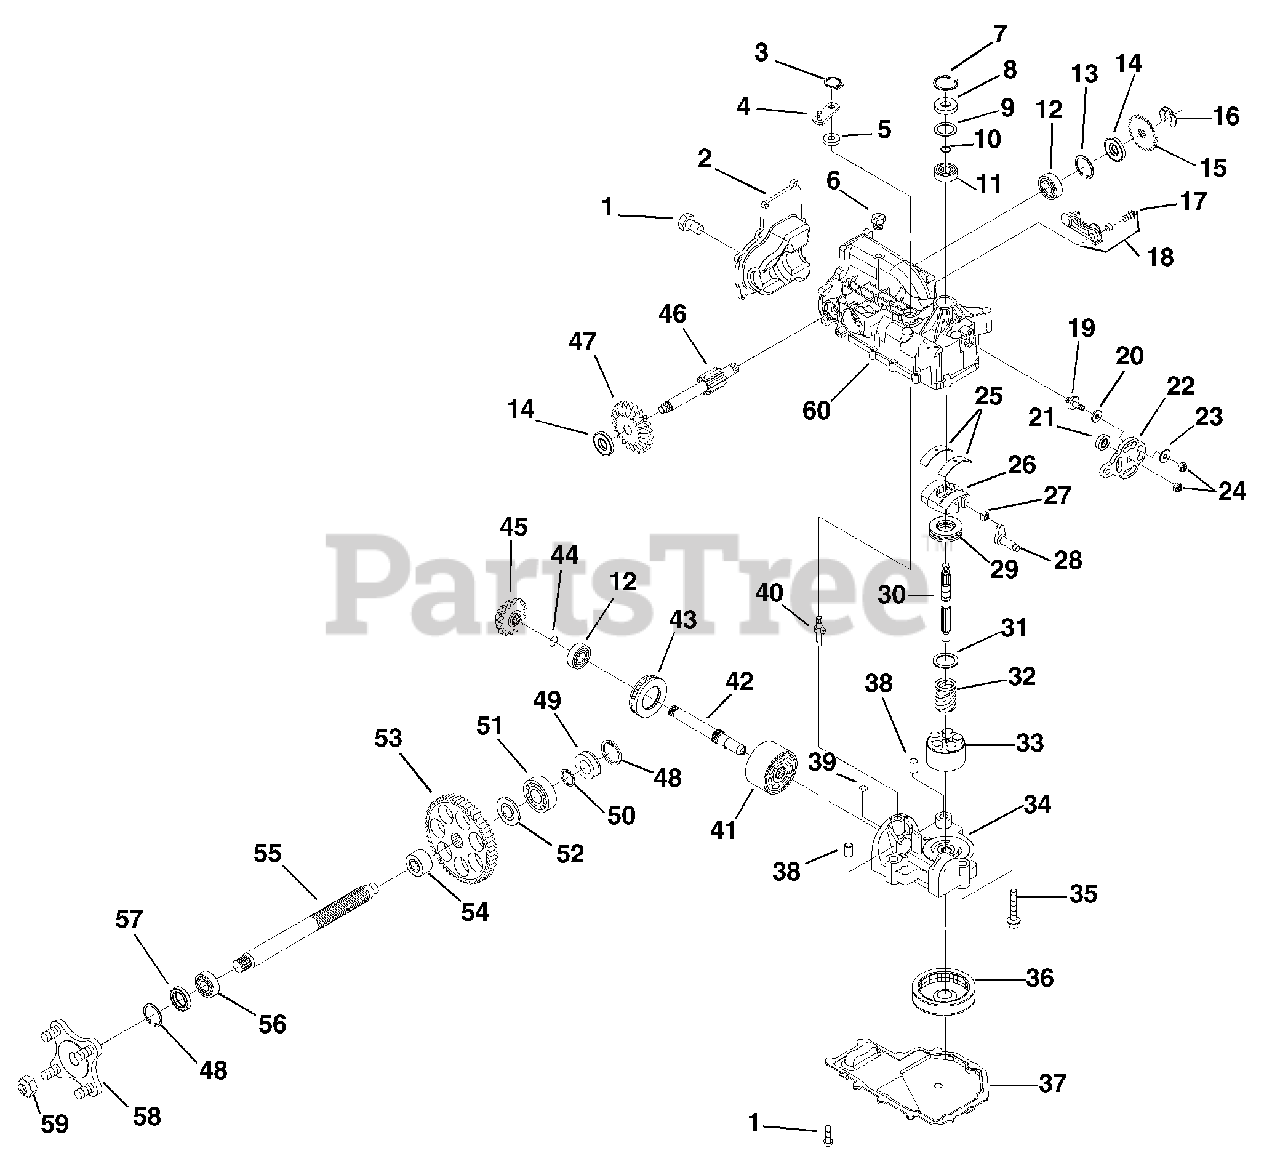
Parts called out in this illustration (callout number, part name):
2	COVER, END IZT
3	RING. RETAINING1
4	ARM. BYPASS
5	SEAL, LIP
6	Plug-Plastic
7	RING. RETAINING
8	SEAL, LIP 15X35X7
9	WASHER .98X1.37X.04
10	RING, WIRE RETAINING
11	BEARING, SHAFT BALL
12	BRG, BALL 17X40X12
13	RING, RET 1.56 INT
14	Seal-Brake Shaft
15	BRAKE, PARK SPLINE
16	Kit-Retaining Ring
17	HFHCS 1/4-20X.875
18	BRAKE ARM, LH IZT
19	STUD. SHORT 5/16-24
20	PACK, FRICTION
21	Seal-Lip
22	Arm-Control
23	WASHER
24	NUT, HEX 5/16-24 NYLON
25	Cradle Bearing
26	SWASHPLATE. VARIABLE
27	GUIDE. SLOT
28	ARM. TRUNNION TAPERED SQUARE
29	BEARING. THRUST 30 X 52 X 13
30	SHAFT, INPUT
31	WASHER. THRUST .59 X .79 X .04
32	SPRING. BLOCK
33	KIT, 10 CC BLOCK
34	Assembly-Center Section
35	HFHCS 3/8-24X2.5 (PATCH)
36	FILTER
37	HSG, IZT LOWER
38	PIN-HOLLOW .39X.5X1.
39	Bypass Plate
40	ACTUATOR, BYPASS
42	SHAFT, MOTOR
43	BRG, THRUST BALL 42X68X16
44	RING, RET WIRE .561 ID
45	GEAR, BEVEL 14T
46	Kit-Brake Shaft
47	GEAR, BEVEL 19T
48	RING, RET 1.87 INT
49	PLUG, SEAL 1.86
50	RING, RET .75 EXT
51	BRG, BALL 20X47X14
52	Bushing-Axle
53	GEAR, SPUR 53T
54	Bushing-Axle
55	AXLE, 1.0X12.3
56	BRG, BALL 25X47X12
57	SEAL, LIP 25X47X7
58	Assembly-Hub
60	Housing-Upper Assembly
